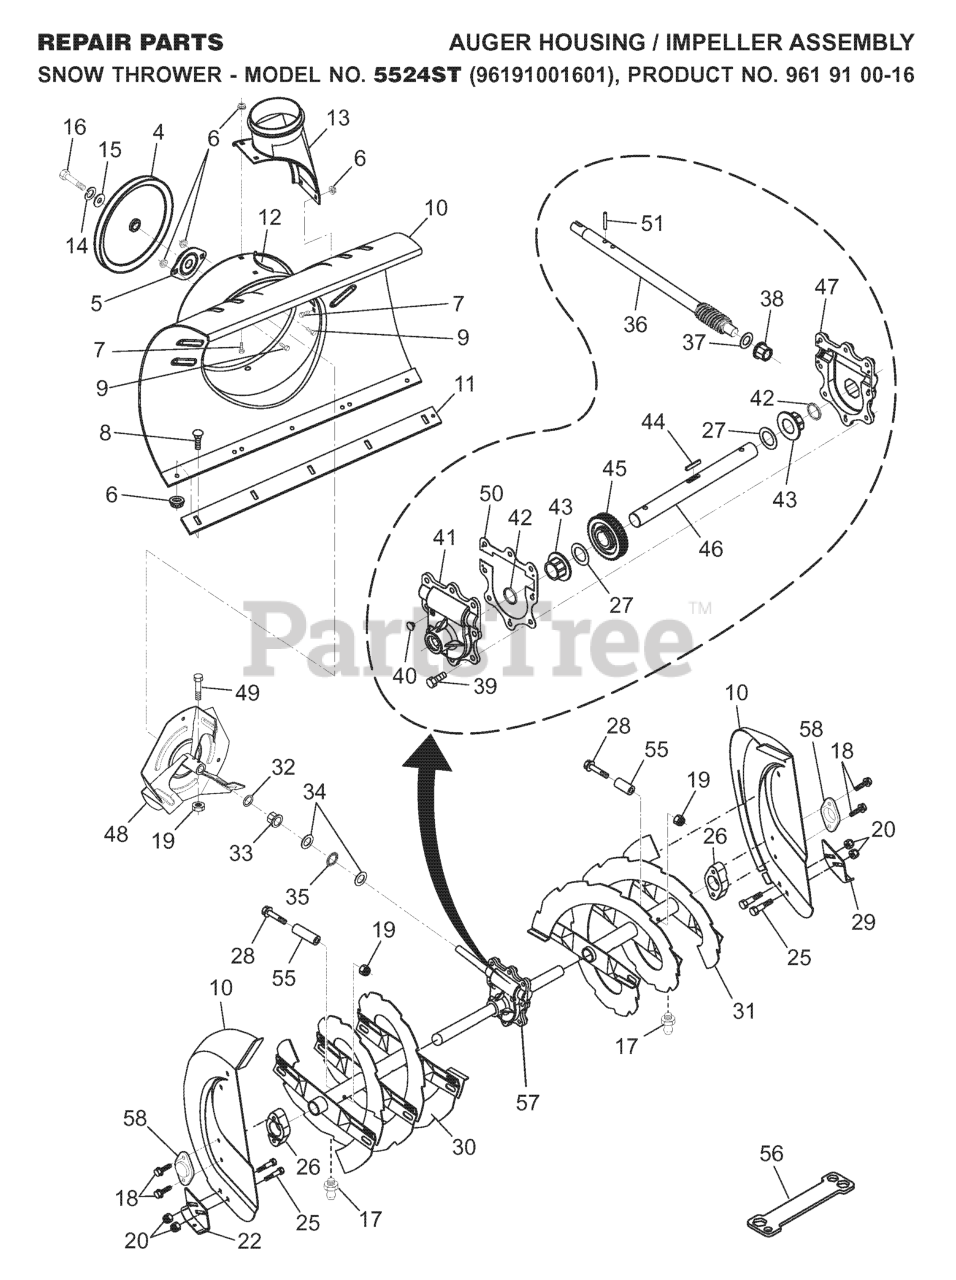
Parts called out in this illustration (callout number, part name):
2	STRETCH DRAWBAR
3	SCREW
4	Washer 13/32 X 3/4 X 16 Ga.
5	BUMPER.RUBBER.HOOD
9	DASH PANEL
10	BOLT D
11	PANEL DASH LH
17	HOOD
18	BUMPER HOOD T
20	PLATE MTG
23	BUSHING.SNAP.NYL.BLK.
25	WASHER
26	NUT
28	GRILL
29	LENS
31	BRACKET.SUPPORT.FENDER
37	Screw 5/16-18 x 1/2 Hex, Self Tapping 5/16-18 x 1/2
38	BRACKET LH PIVOT
39	BRACKET RH PIVOT
51	LOCKNUT.NYLOC.1/4-20
53	BRACKET PNT PICK OFF LT/PL
57	BOLT
58	AIR DUCT P/L/LT
60	Bolt - Rd. Hd. Sq. Neckiage 3/8 16 x 3/4
64	DASH LOWER
68	NUT
109	BRACKET BUMPER
110	PLUG PLASTIC
115	SCREW
134	ROD SUPPORT HOOD LT/PL HUS.
140	BRACKET SUSPENSION FRONT
142	PLATE
143	BRACKET, SWAY BAR
144	BRACKET FOOTREST
145	ROD PIVOT CHASSIS/HOOD
159	CUPHOLDER
